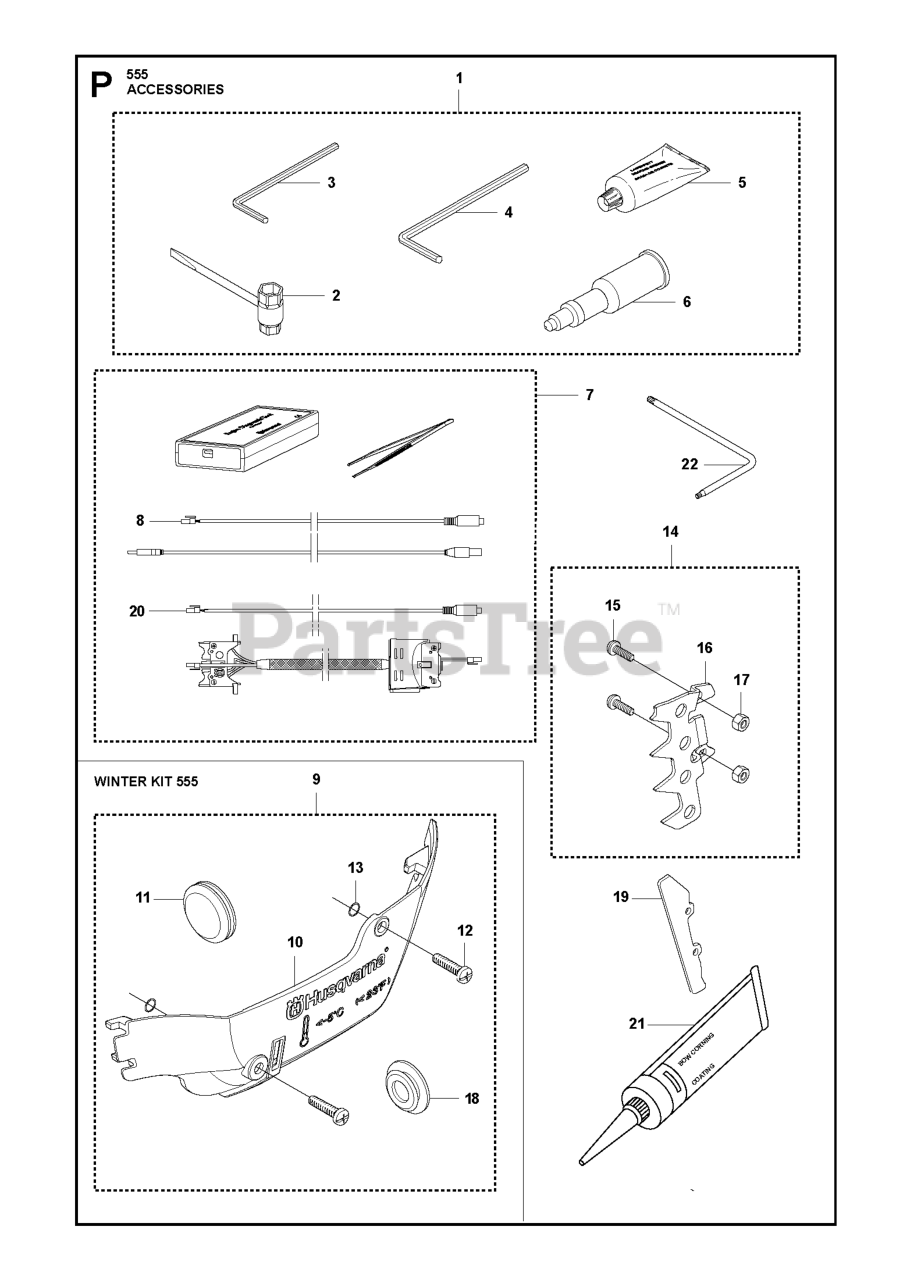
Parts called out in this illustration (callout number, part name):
2	COMBINATION WRENCH
5	GREASE
6	Grease Gun
7	DIAGNOSTIC TOOL KIT
8	CABLE ASSY
9	WINTER KIT
10	WINTER COVER
14	SPIKE OUTER
15	SCREW ITXPANM M5X16 T27 10.9
16	SPIKE OUTER
18	WINTER PLUG
19	RP ENCLOSED KIT
20	CABLE ASSY
